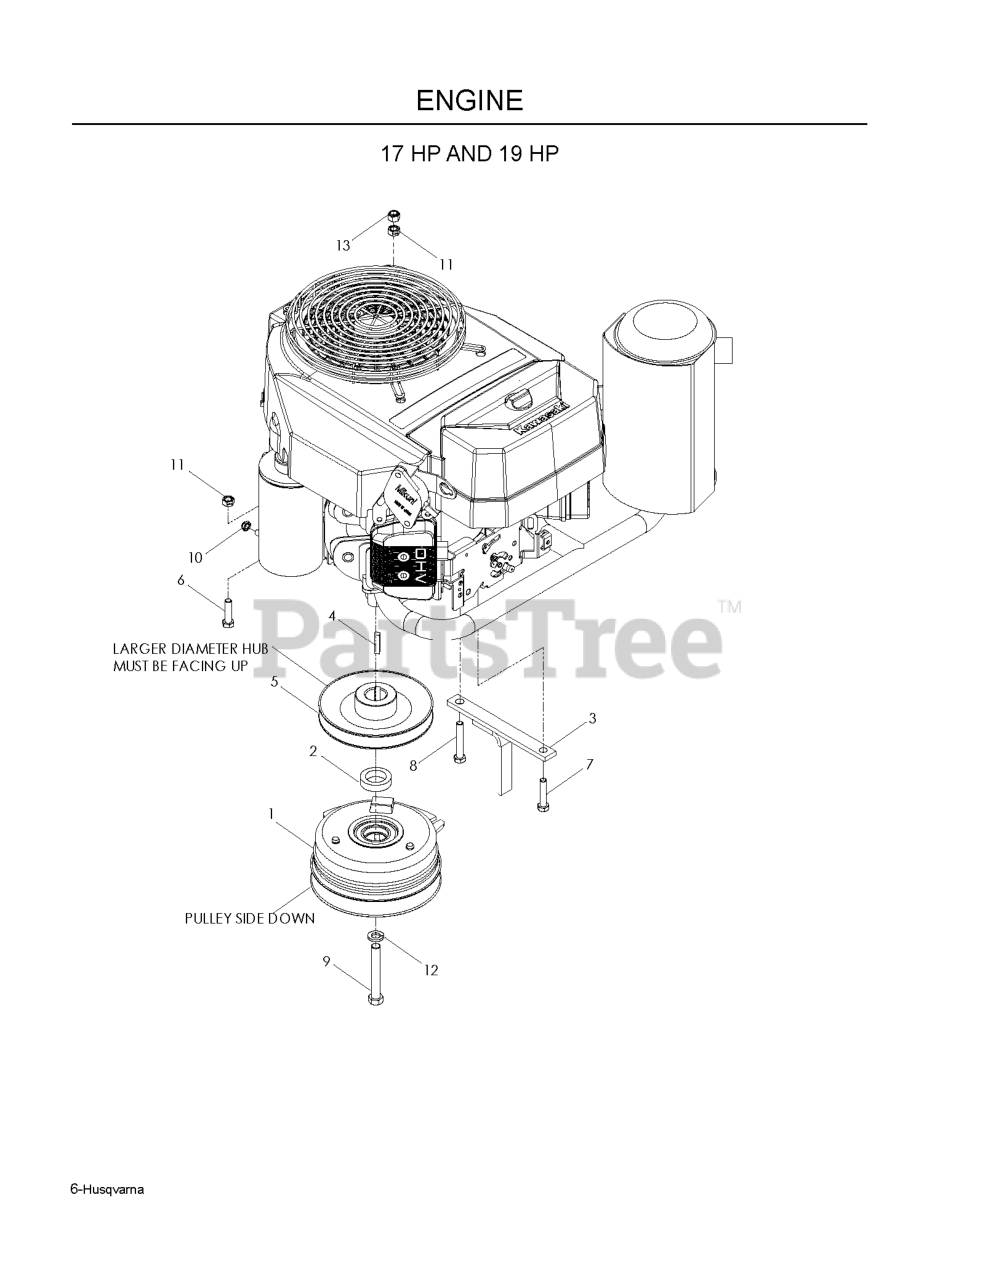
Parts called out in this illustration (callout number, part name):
1	CLUTCH 125 FT/LB
3	CLUTCH TIE DOWN
4	KEY 1/4 SQ X 1 1/8
6	HCS 5/16C X 1 1/4
7	CAPSCREW 5/16 X 1/1/2 HEX HEAD
8	HCS 5/16-18X2
9	HEX SCREW 7/16-20 X 3
10	JAM NUT 1/4C (2 2 PW01)
11	NUT 5/16C CENTERLOCK
12	WASHER 7/16 LOCK
13	NUT 5/16 NYLOC
